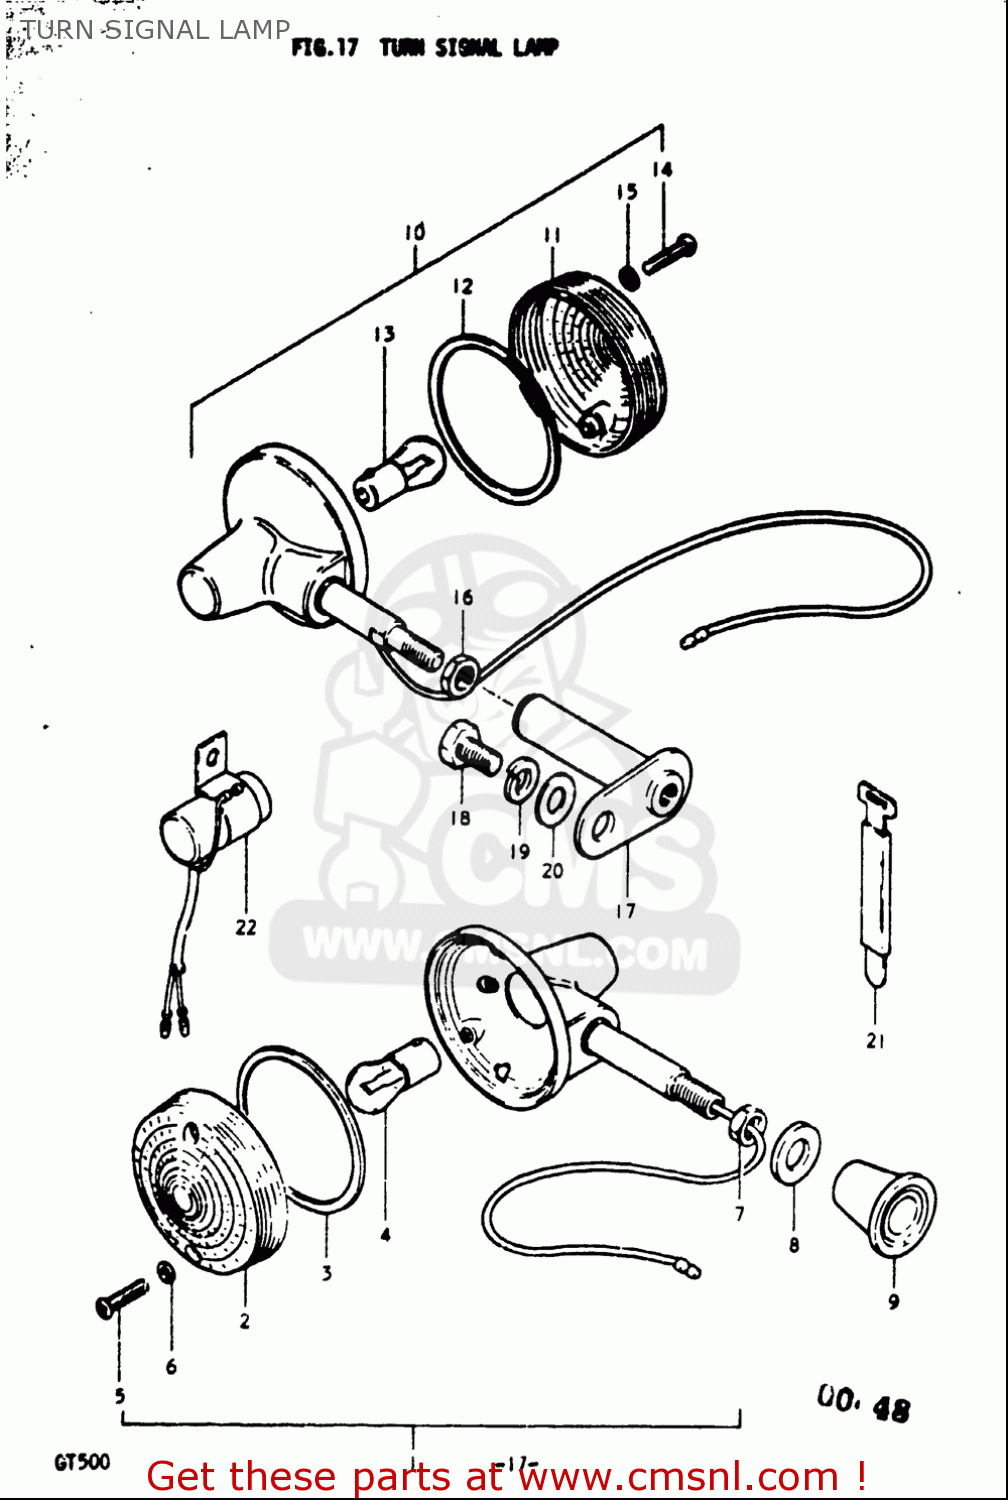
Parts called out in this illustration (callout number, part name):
2	LENS
3	GASKET (NAS)
4	BULB(12V23W,STANLEY,A4577A)
6	GASKET (NAS)
7	NUT
8	WASHER
9	COVER,FRONT TURN SIGNAL BRACKET
10	LAMP ASSY,RR TURNSIGNAL
11	LENS
12	GASKET (NAS)
13	BULB(12V23W,STANLEY,A4577A)
15	GASKET (NAS)
16	NUT
18	BOLT
19	WASHER,LOCK
20	WASHER (10.5X24X2.3)
21	CLAMP
22	RELAY,TURN SIGNAL
